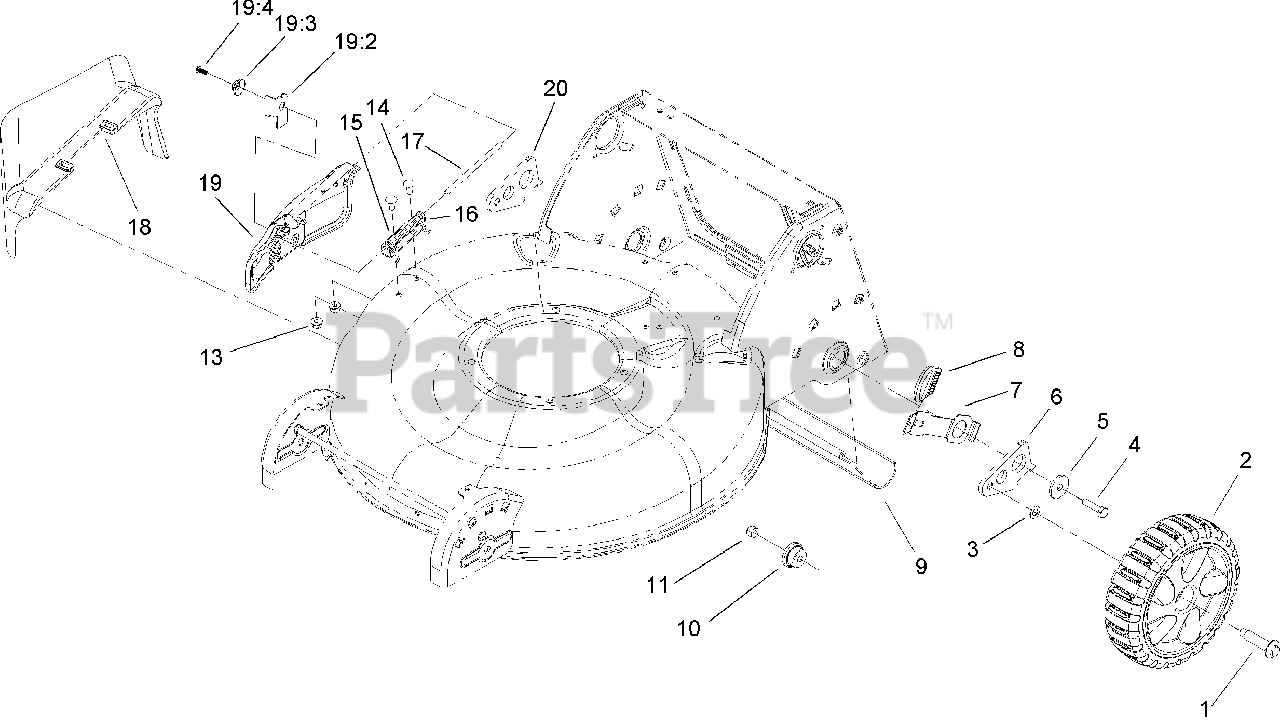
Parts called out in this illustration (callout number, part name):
1	BOLT-SHOULDER
2	8 IN WHEEL ASM
4	SCREW-HH
5	Washer-Flat
6	ARM-PIVOT, REAR (LH)
7	ARM-SPRING, REAR
8	KNOB-LEVER, HOC
9	SHIELD-TRAILING
10	Bushing-Mount, HOC
11	NUT-LOCK, NI
14	SCREW-CARR
15	SPRING-TORSION
16	BRACKET-COVER
17	ROD-COVER
18	CHUTE-DISCHARGE, SIDE
19	DISCHARGE DOOR ASM
19:2	LATCH-DOOR
19:3	CAP-DOOR
19:4	SCREW-PLASTITE
20	ARM-PIVOT, REAR (RH)
